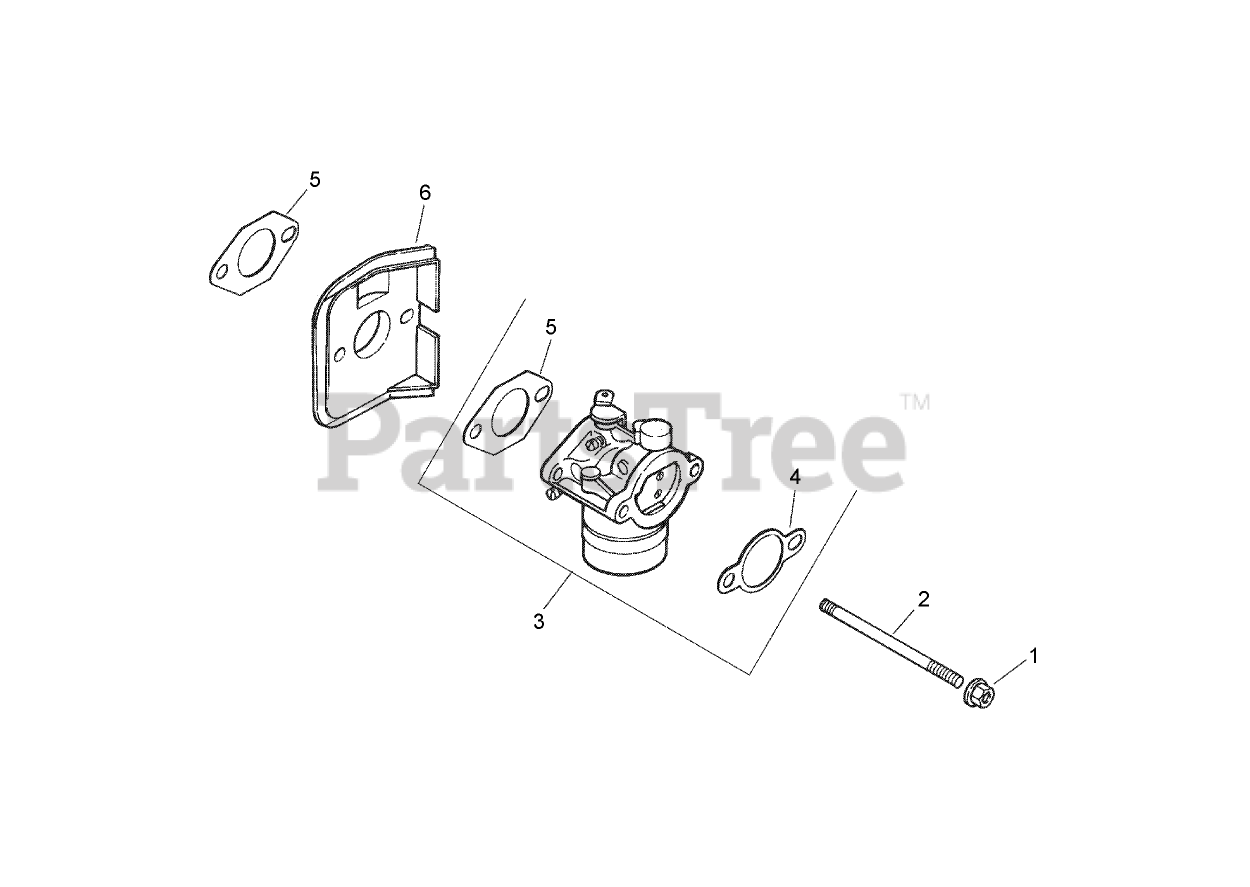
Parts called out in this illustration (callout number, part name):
1	NUT-FLANGE (M6X1.0)
2	Stud (M6x1.0x116)
3	Carburetor Kit (Includes 4, 5 )
4	Gasket-Base, Air Cleaner
5	Gasket-Carburetor
6	Deflector-Heat
